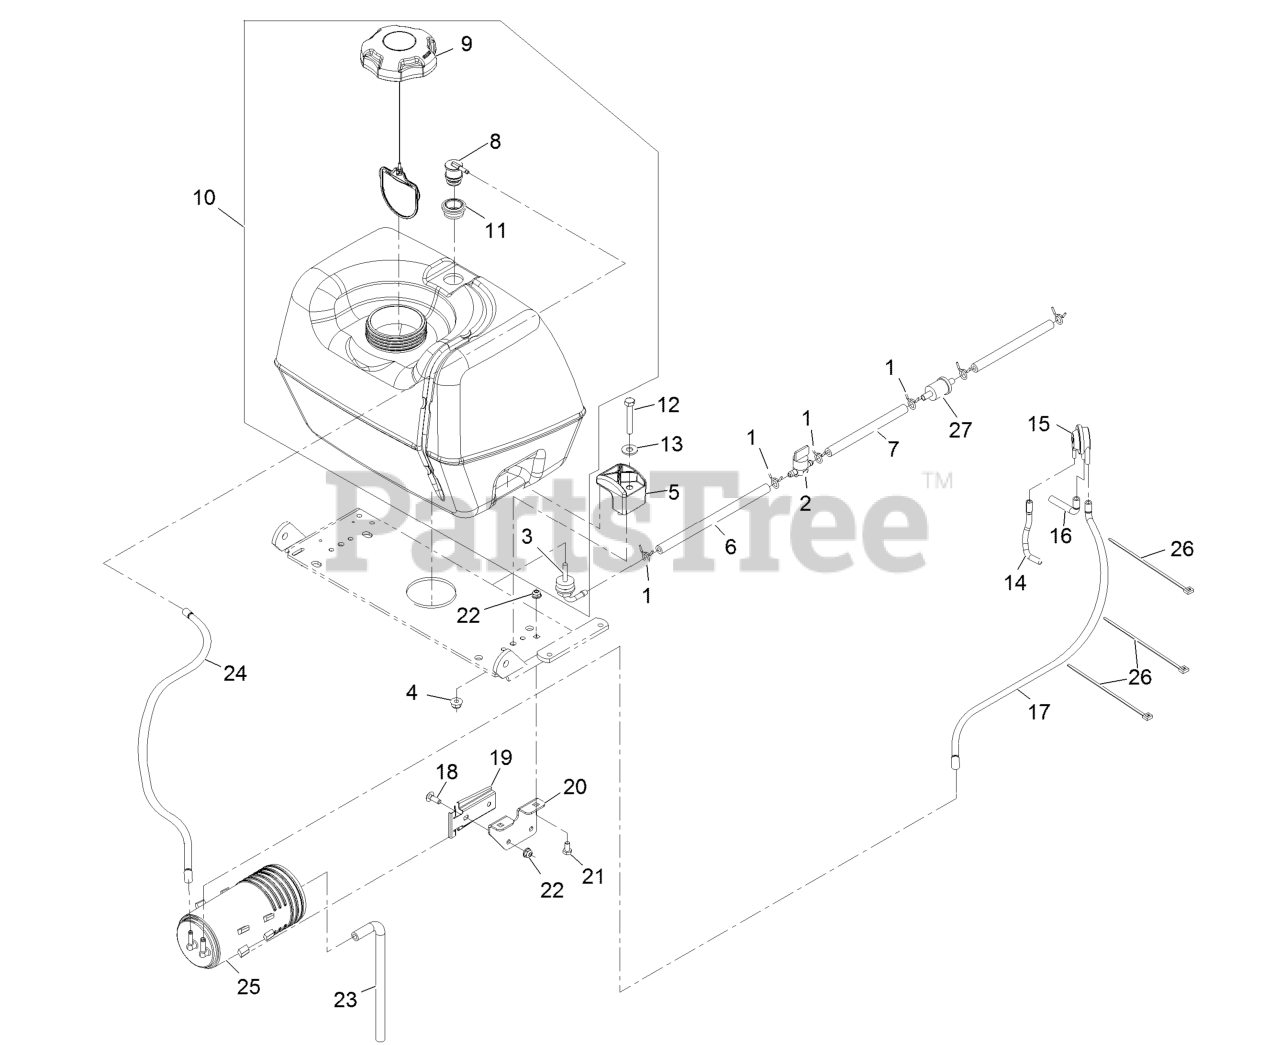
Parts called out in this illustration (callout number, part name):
1	CLAMP-HOSE
2	VALVE-FUEL
3	FITTING-FUEL, BULKHEAD
4	NUT-HF, NI
6	HOSE-FUEL
7	HOSE-FUEL
11	GROMMET
12	SCREW-HH
13	WASHER-FLAT
14	HOSE-VENT, FORMED
15	VALVE-CONTROL, VACUUM
16	HOSE-VENT, FORMED
17	HOSE-VENT, FORMED
18	SCREW-HH
19	BRACKET-CANISTER, CARBON
20	BRACKET-CANISTER, CARBON
21	BOLT-CARR
23	HOSE-VENT, CANISTER
24	HOSE-VENT
25	CANISTER-CARBON, 800CC
26	TIE-PLASTIC
27	Pn 49019-0014 Filter W/6in Fuel Line
